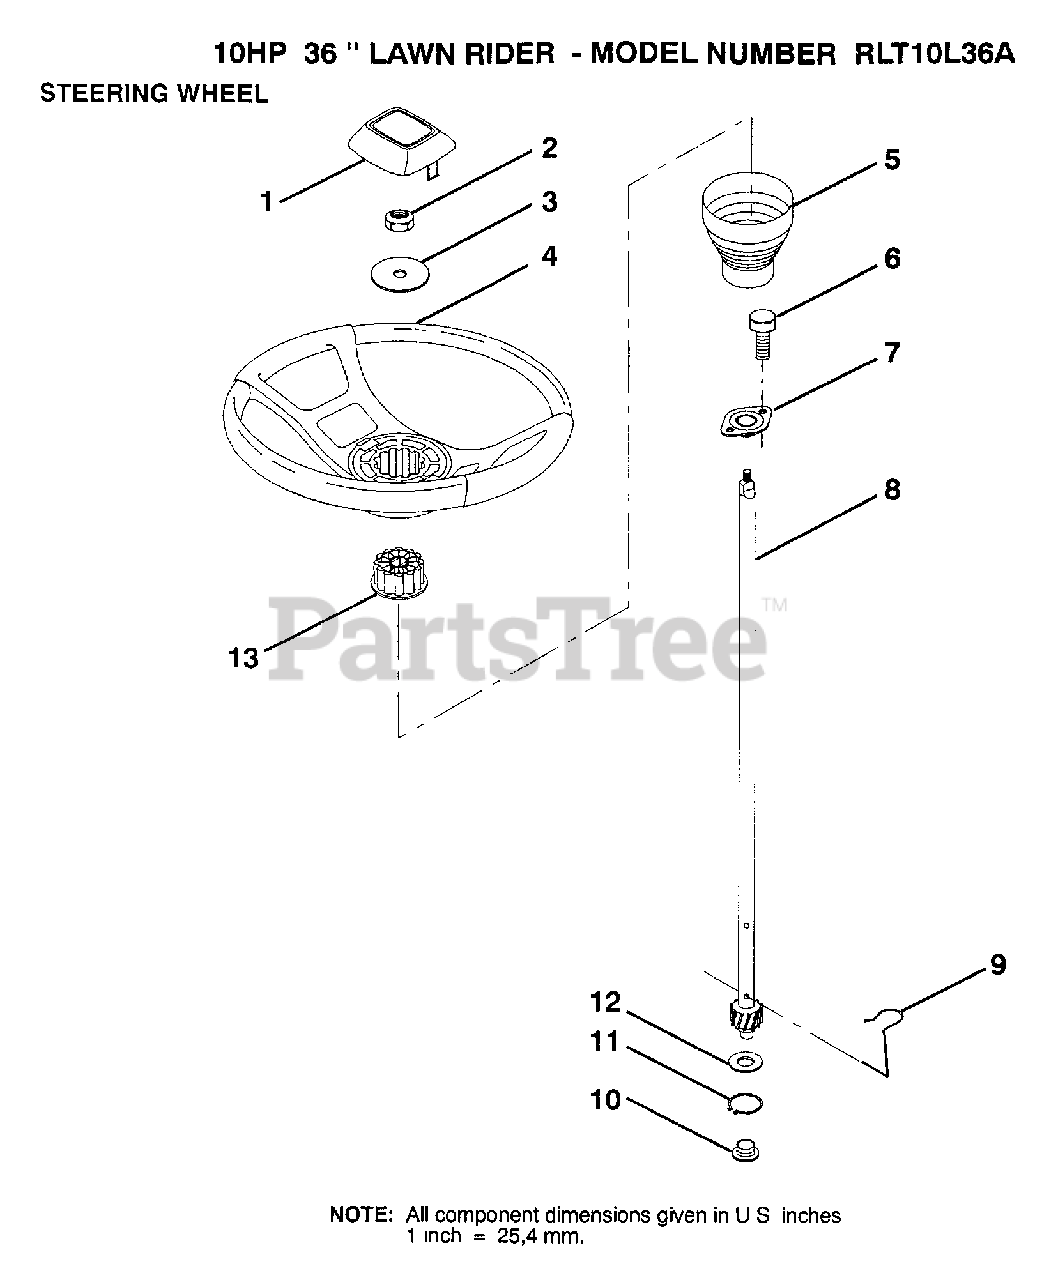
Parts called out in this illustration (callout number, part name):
1	ST WHL INSERT CAP
2	GRIPCO NUT
3	WASHER T
5	SLEEVE STEERING
9	STEERING CLIP
10	BUSHING STEER LWR
11	RING
12	WASHER LT
13	ADAPTER-WHEEL LT
